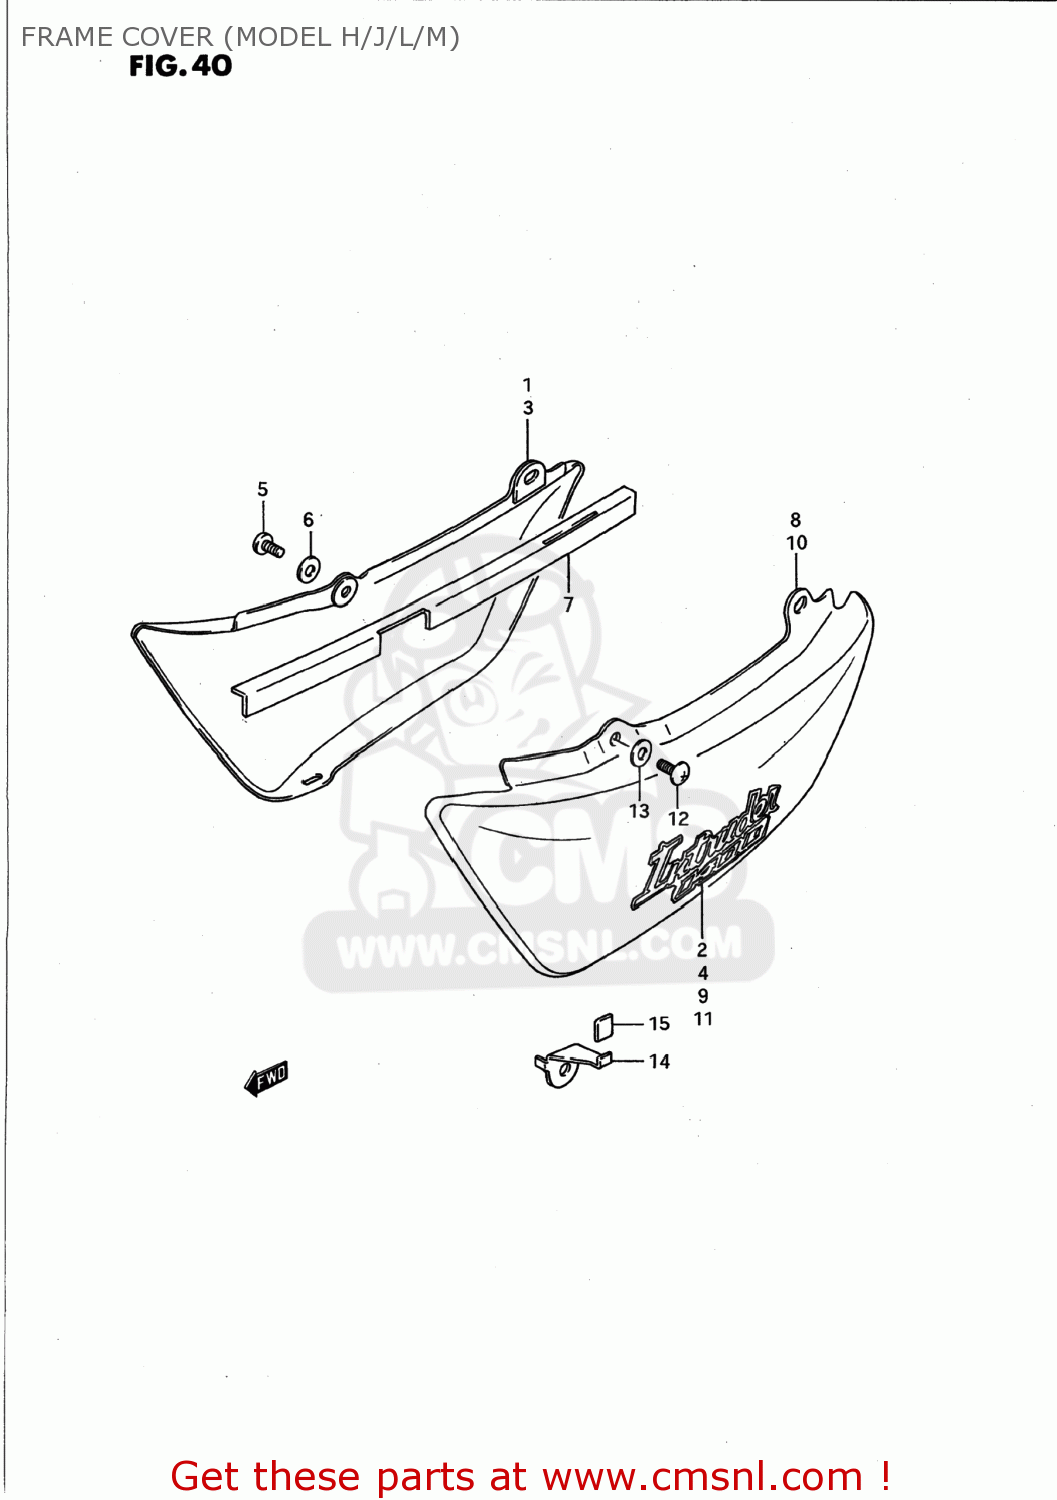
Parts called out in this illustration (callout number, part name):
1	1-2
2	EMBLEM,FRAME COVER
3	3-2
4	EMBLEM
5	SCREW 6X12
6	WASHER(6.5X18X1.6)
7	PROTECTOR,FRAME COVER,R
8	COVER,FRAME,LEFT
9	EMBLEM,FRAME COVER
10	COVER ASSEMBLY,FRAME,LEFT
11	EMBLEM
12	SCREW 6X12
13	WASHER(6.5X18X1.6)
14	HOOK,FRAME COVER,L
15	CUSHION,FRAME COVER HOOK
